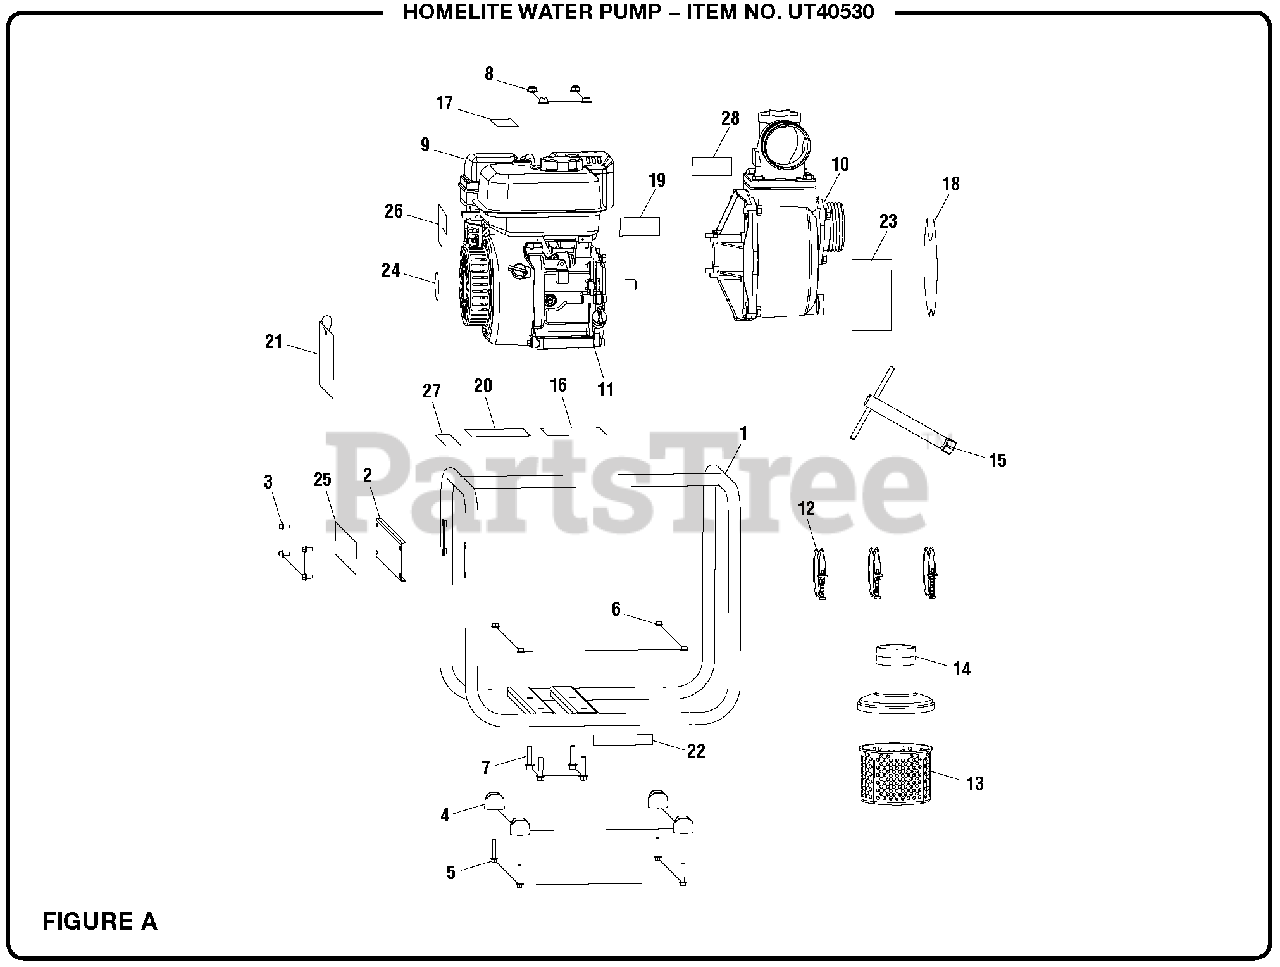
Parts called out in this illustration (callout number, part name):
1	Frame Assembly
2	Front Panel
3	Bolt (M6 x 12 mm)
4	Rubber Foot
5	Bolt (M6 x 35 mm, Flange Hd.)
6	Lock Nut (M6, Flange Hd.)
7	Bolt (M8 x 35 mm, Flange Hd.)
8	Lock Nut (M8)
10	Pump Assembly
11	Output Shaft Key
12	Hose Clamp
14	Filter Cap
15	Spark Plug Wrench
16	Hot Surface Label
17	CPSC Label
18	Danger Label
19	E85 Label
20	Combustion Label
21	Danger Hangtag
22	Lubricant Label
23	Quick Start Label
24	Recoil Housing Label
25	Performance Label
26	Choke Label
27	EMC Label
28	Do Not Operate Label
